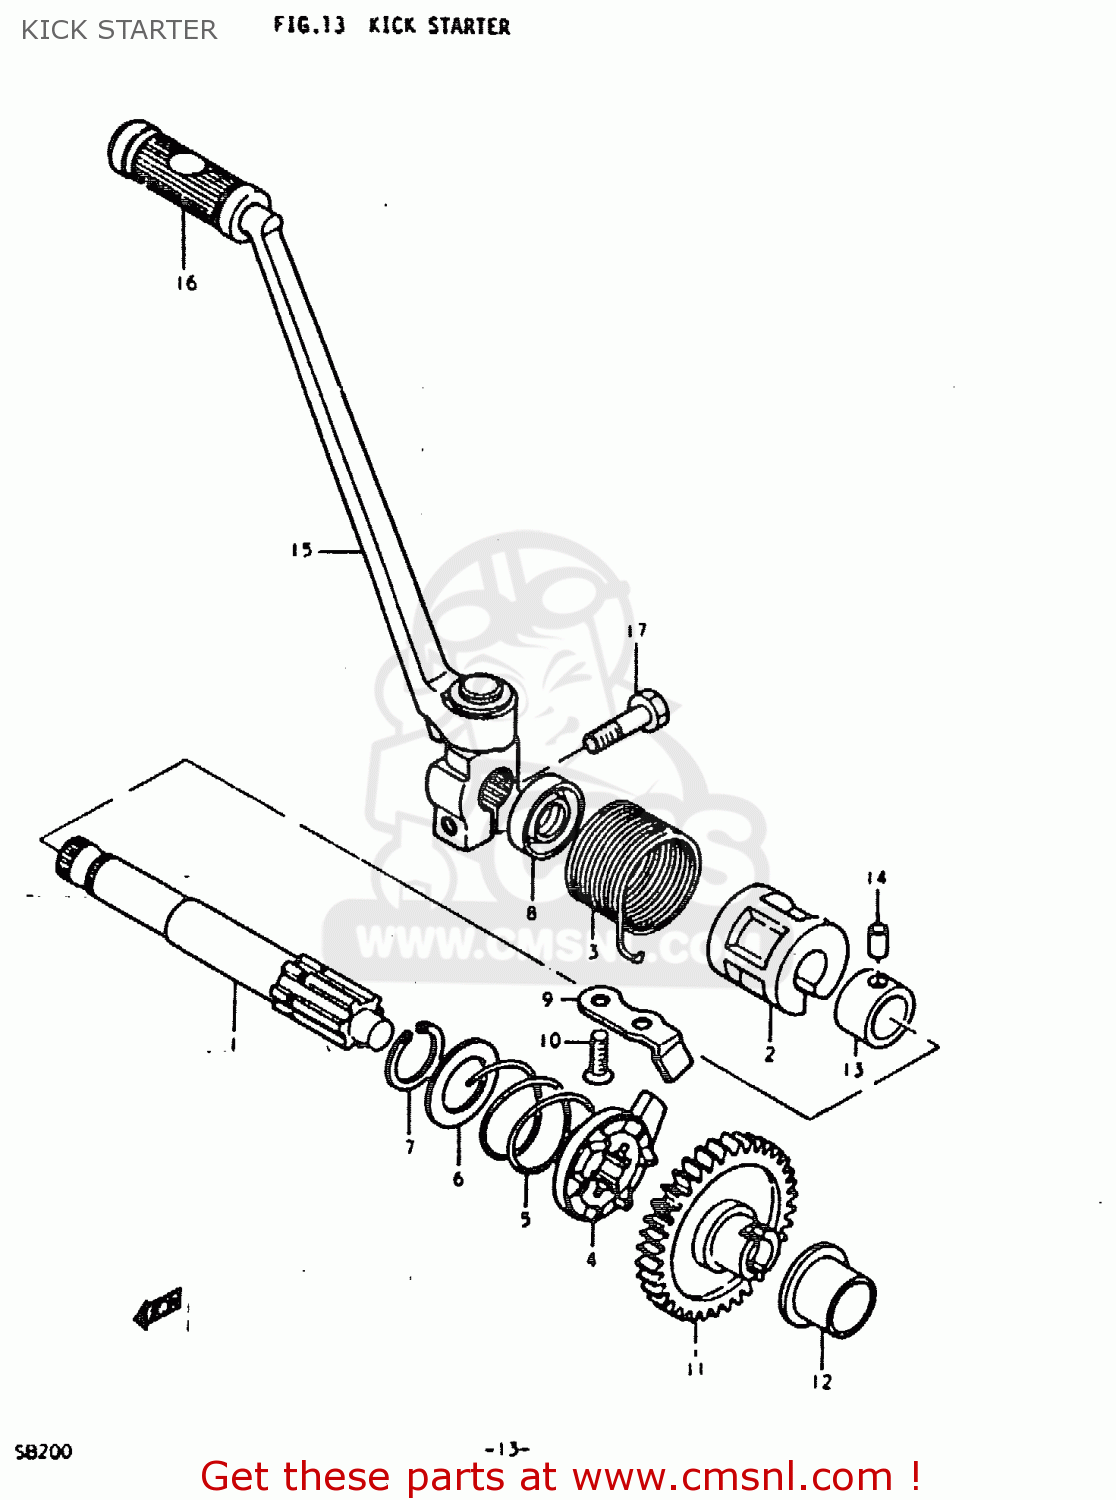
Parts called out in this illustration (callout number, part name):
1	SHAFT, KICK STARTER
2	GUIDE,KICK SHAFT SPRING
3	SPRING
4	STARTER,KICK
5	SPRING
6	PLATE
7	CIRCLIP
8	SEAL,OIL(16X30X8)
9	GUIDE,KICK STARTER
10	SCREW
11	GEAR, DRIVE
12	BUSHING
13	BUSHING
14	PIN
15	LEVER ASSY,KICK STARTER
16	RUBBER,KICK STARTER PEDAL
17	BOLT
